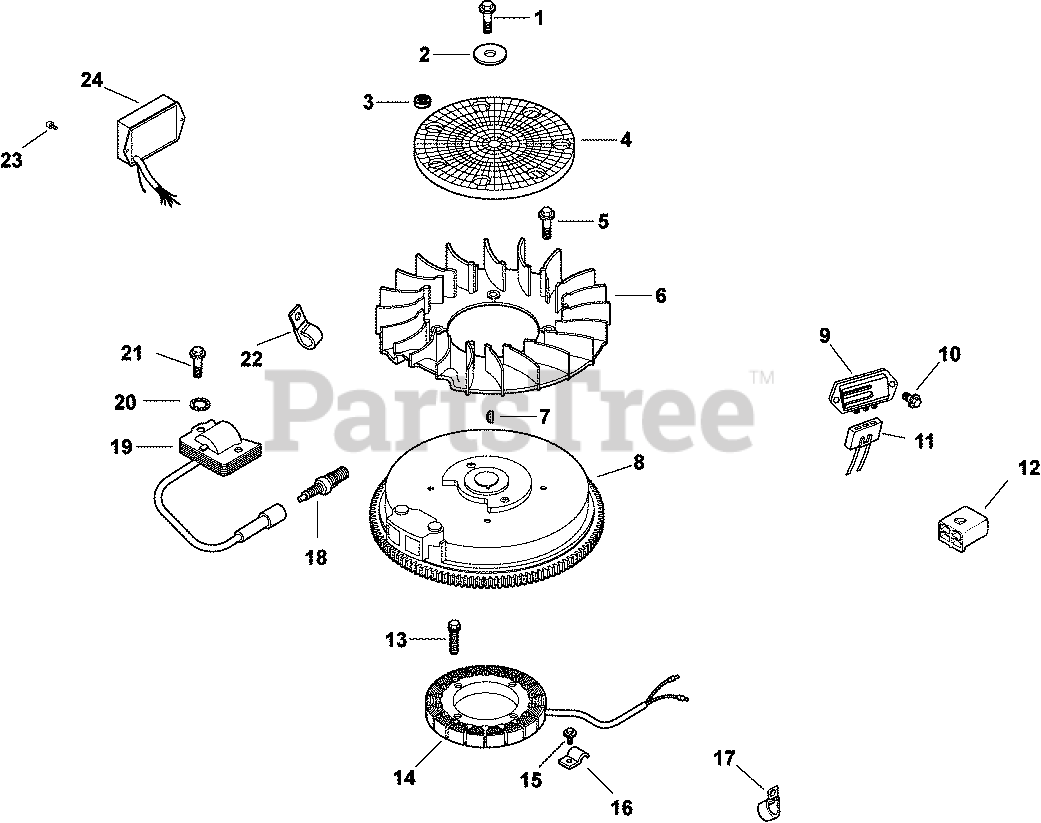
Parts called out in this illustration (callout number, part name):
1	SCREW, FLG M10X1.5X45 - (#25086361S)
2	WASHER, FLAT 13/32"
4	SCREEN, GRASS
5	BOLT, SHOULDER
7	KEY, 3/16" X 5/8"
8	FLYWHEEL - DISCONTINUED
9	REG/RECT-15 AMP (KM)-USE 41 403 10-S
10	SCREW, PHL HD #11-16X7/8"
11	CONNECTOR, BODY (KM)-USE 25 155 41-S
12	CONNECTOR
13	SCREW, M5X0.8X25 - (#25086402S)
14	KIT, 15 / 20 AMP STATOR
15	SCREW, FLG THD FRM M5X.8X10
17	CLIP, HOSE - (#DSC)
18	PLUG, SPARK (STD)
19	MODULE, IGNITION
20	WASHER, INT TOOTH LOCK 1/4"
21	SCREW, SCKT THRD FRMM5X0.8X20 - DISCONTINUED
22	CLIP, CABLE
23	SCREW, PHL THD FRM M4.2X13
24	MODULE, DIGITAL SPD ADV-USE 12 707 01-S
